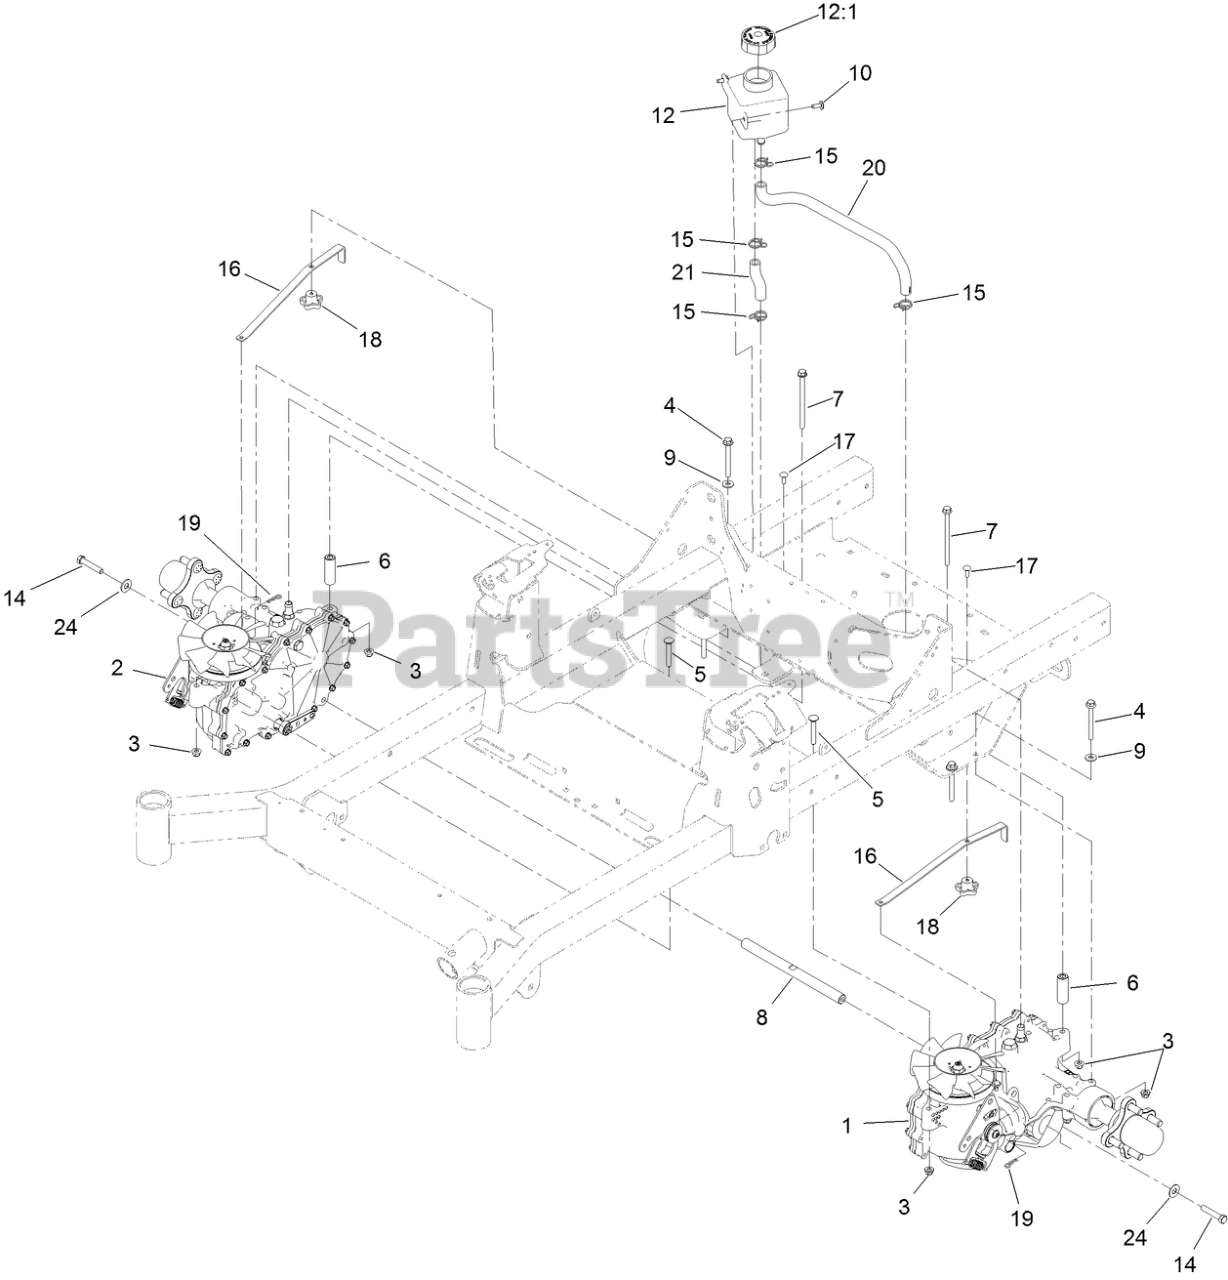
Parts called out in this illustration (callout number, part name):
1	LH TRANSAXLE ASM
2	RH TRANSAXLE ASM
3	NUT-HF, NI
4	SCREW-HHF
5	BOLT-CARR
6	SPACER-HYDRO
7	SCREW HHF
8	SHAFT-SPACER
9	WASHER-SPRING
10	SCREW-TORX
12	TANK-HYD
12:1	CAP-RESERVOIR, HYD
14	SCREW-HH W/LOCTITE
15	CLAMP-HOSE
16	ARM-BYPASS, HYDRO
17	BOLT-CARR
18	KNOB-HANDLE
19	PIN-COTTER
20	HOSE-HYDRAULIC
21	HOSE-HYDRAULIC
24	WASHER-FLAT
